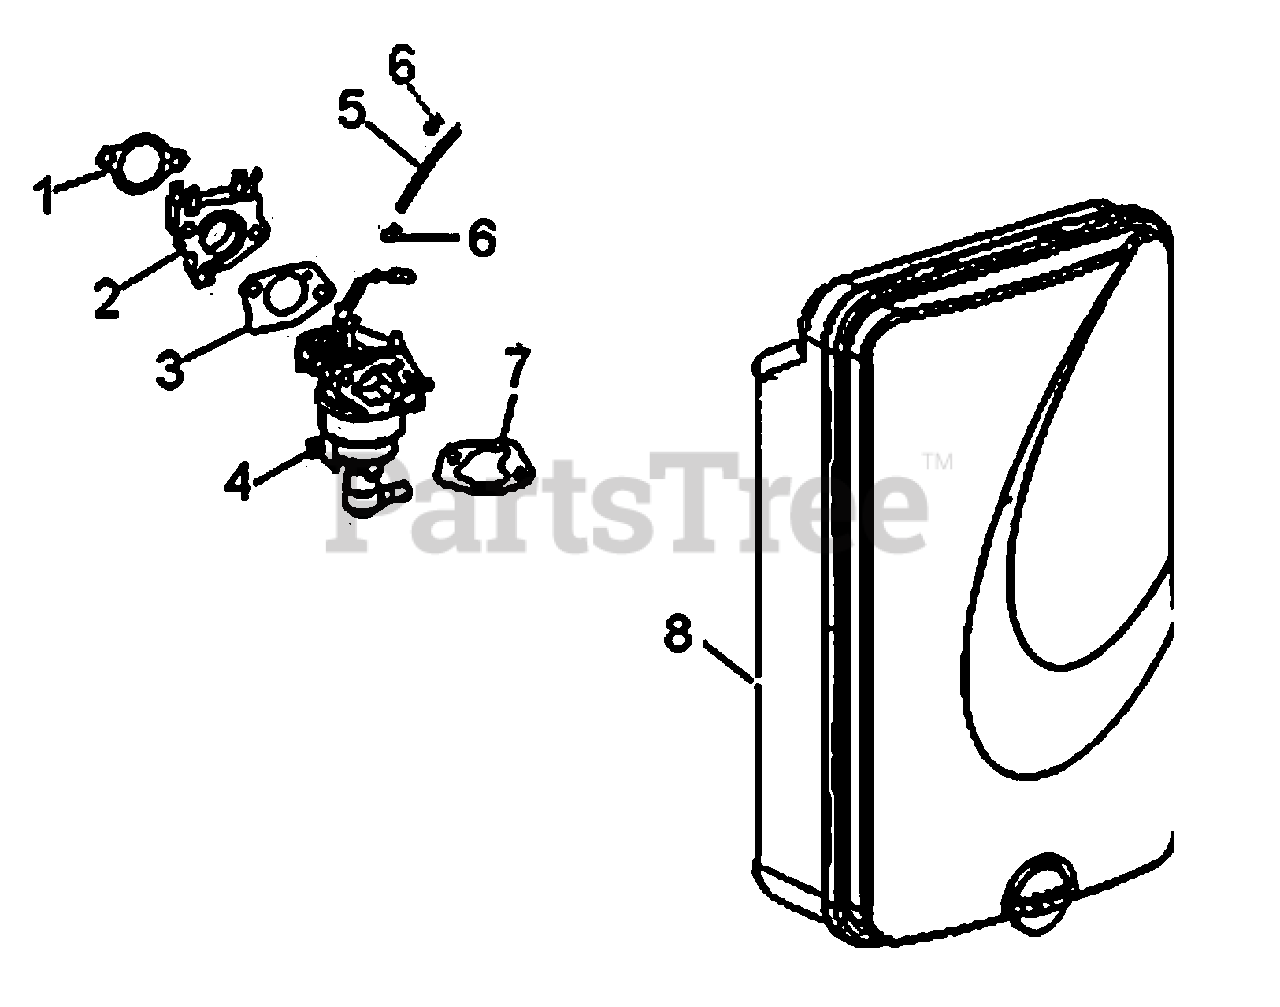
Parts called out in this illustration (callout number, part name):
1	PACKING, INSULATOR
2	SPACER, CARBURETOR
3	GASKET, CARBURETOR
4	CARBURETOR ASSY
5	TUBE, FUEL
7	GASKET, CARBURETOR
8	AIR CLEANER
